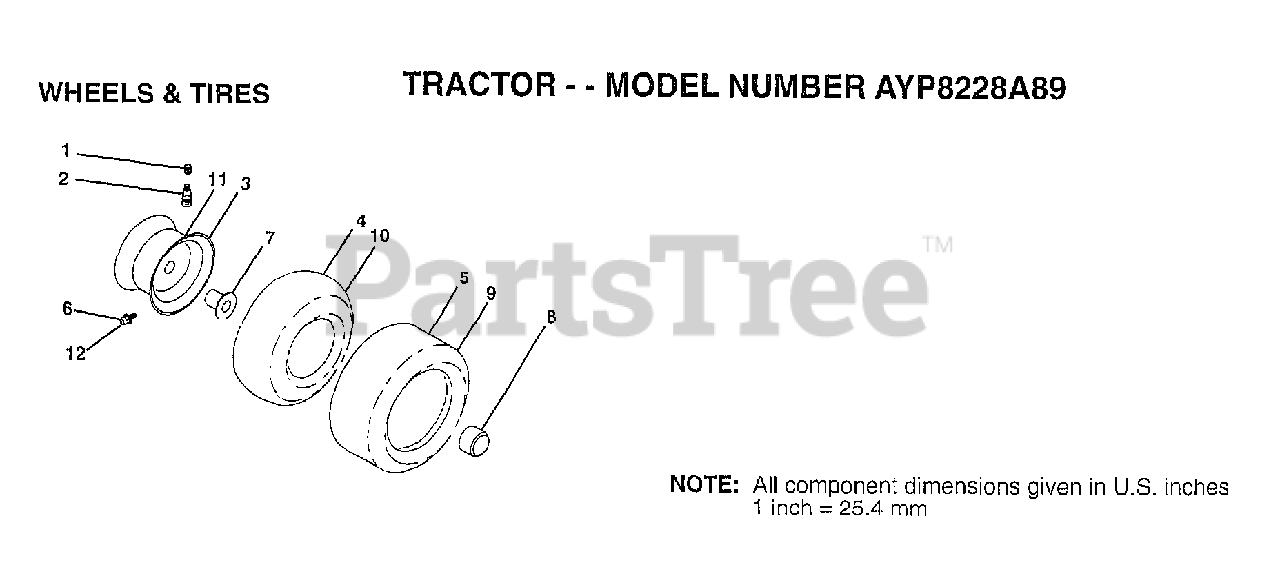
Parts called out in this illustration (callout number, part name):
1	VALVE CAP
2	VALVE STEM LT
3	"RIM ASM 8"" FRT"
4	TUBE.16X6.5/7.5-8
6	FITTING LT
7	"FLANGE, BEARING"
8	HUB CAP
8	"RIM ASM 12"" REAR"
10	TUBE.23X8/10-12
11	"RIM ASM 12"" REAR"
12	ZERK FITTING M
